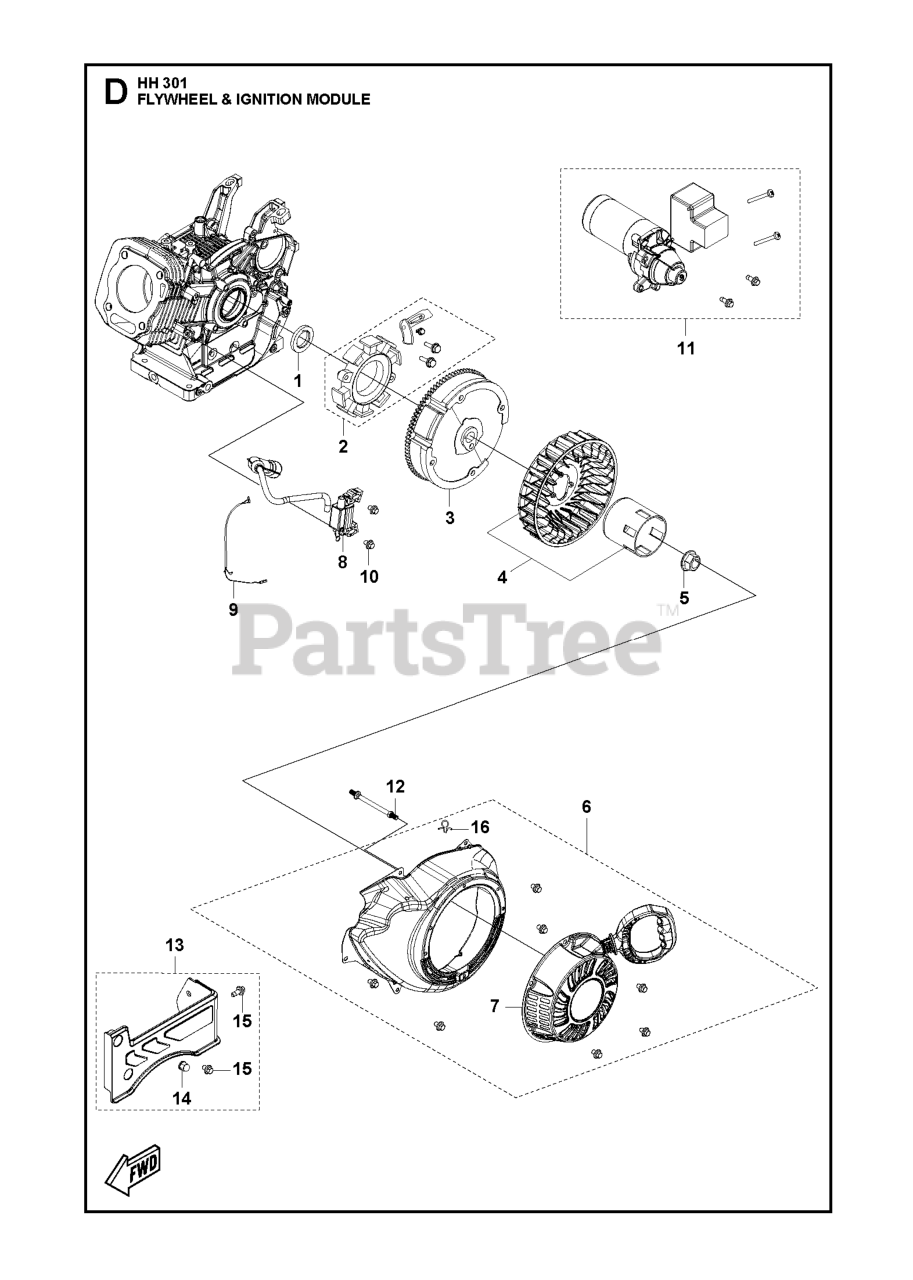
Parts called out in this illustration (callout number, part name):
1	SEAL OIL SEAL
2	COIL CHARGE COIL KIT
6	STARTER ASSY
7	STARTER HANDLE ASSY
8	IGNITION COIL
9	WIRE IGNITION COIL STOP ENGINE
10	BOLT
11	STARTER MOTOR
13	PLATE KIT
15	BOLT
